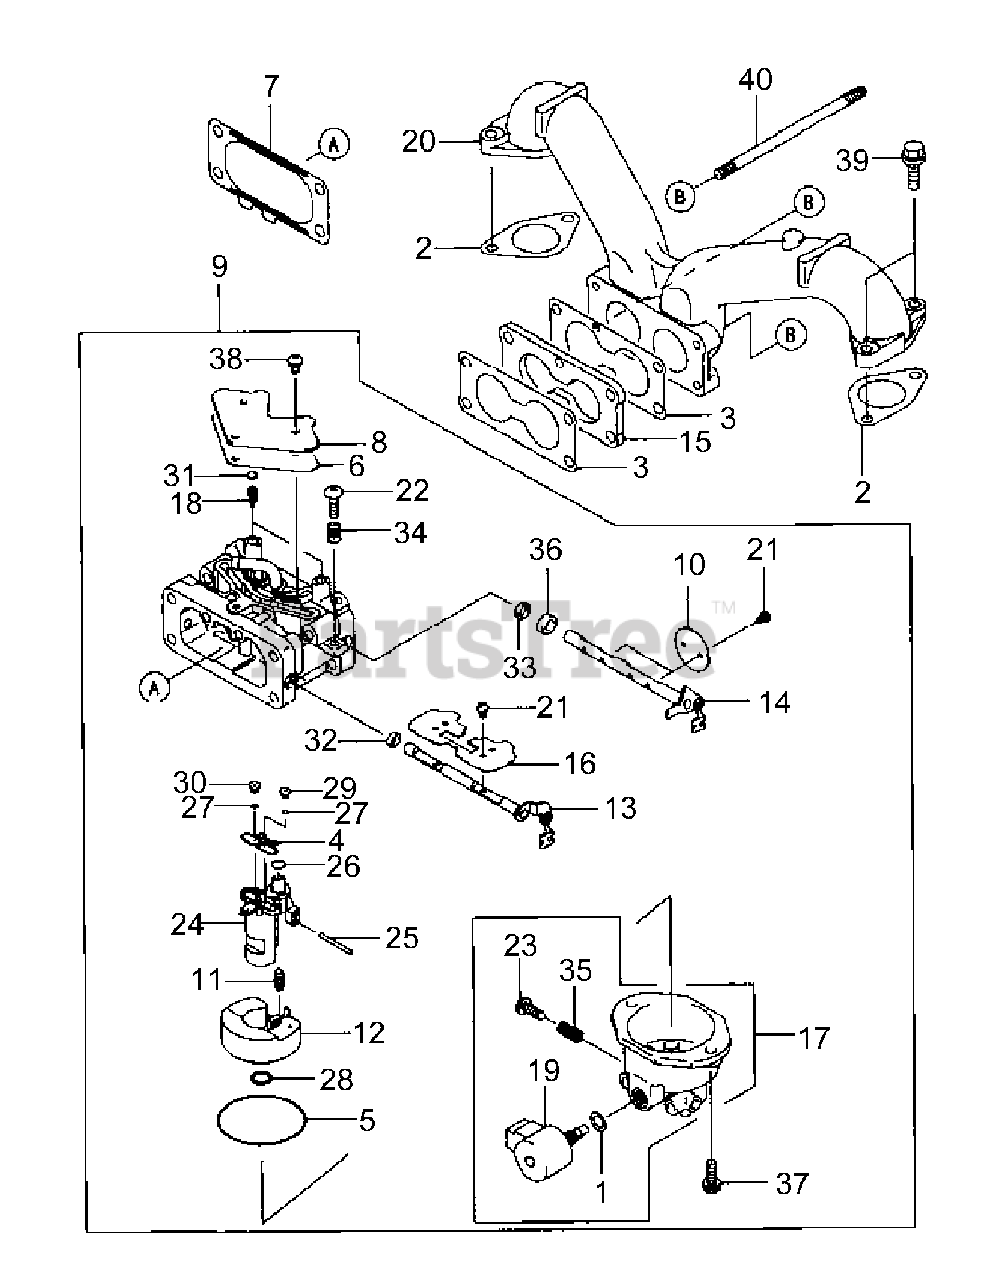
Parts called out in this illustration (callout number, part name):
2	MANIFOLD GASKET
3	CARBURETOR GASKET
9	CARBURETOR ASSY.
10	THROTTLE VALVE
13	CARBURETOR SHAFT
14	CARBURETOR SHAFT
17	FLOAT CHAMBER ASSY.
20	INTAKE MANIFOLD
29	MAIN JET #104
30	MAIN JET #108
31	EXPANSION PLUG
39	FLANGED BOLT
